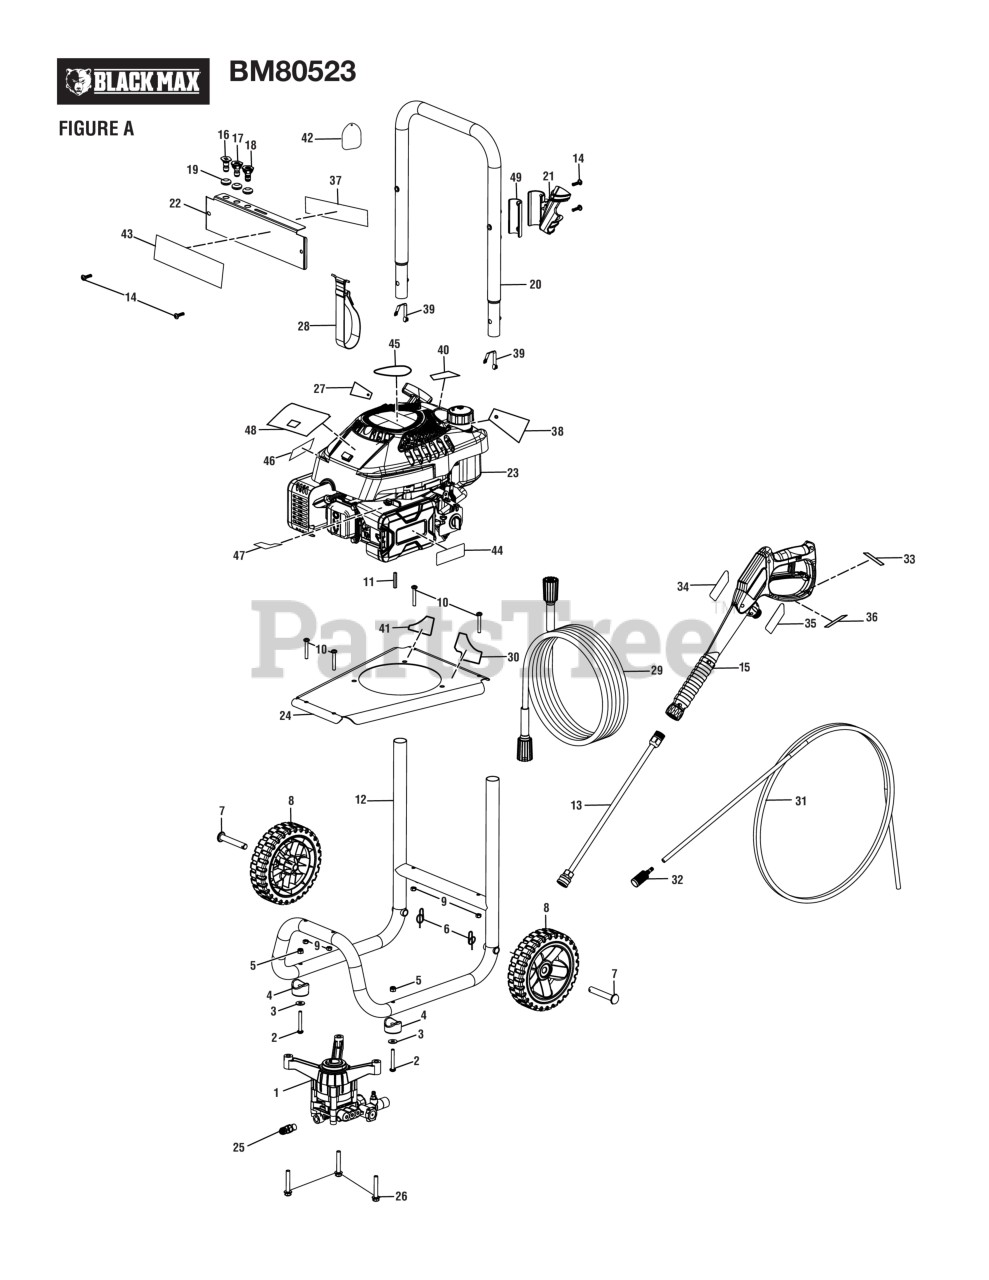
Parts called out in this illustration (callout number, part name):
1	PUMP, HIMORE ALUM HEAD, VERTICAL, 2300PS
2	Screw (1/4-20 x 1.85 in., T30 Torx Pan Hd.)
3	Washer (1/4 in.)
4	Rubber Foot
5	Lock Nut (1/4-20 in.)
6	Hitch Pin
7	Wheel Axle
8	WHEEL ASSEMBLY
9	Lock Nut (M6 x 1)
10	Bolt (M6 x 42 mm, T30 Torx Hex Hd.)..
11	Output Shaft Key (3/16 x 35 mm)
12	Main Frame Assembly
13	Spray Wand Assembly
14	Screw (M6 x 20 mm, Phillips Hd.)
15	Trigger Handle
16	Soap Nozzle (Blue)
17	Nozzle, 25° (Green)
18	40deg Nozzle
19	Rubber Nozzle Grommet
20	Handle Assembly
21	Trigger Handle Holder
22	Face Panel
23	Engine
24	ENGINE PLATE
25	Thermal Release Valve.
26	Hex Bolt (M8 x 50 mm, Flange Hd.)
27	Label (Oil Dipstick Hangtag)
28	Hose Holder Strap
29	HOSE, 25 FEET, 1/4 INCH
30	Add Oil Label
31	Detergent Injection Tube
32	Detergent Injection Filter
33	Label (Trigger Handle Warning, French & Spanish)
34	Trigger Handle Logo Label
35	Trigger Handle Warning Label (English)
36	Trigger Handle Rating Label
37	Quick Start Label
38	Danger Hang Tag
39	Lock Button w/Spring Clip
40	No E85 Label
41	LABEL, DANGER, ENGLISH ONLY
42	Nozzle Hang Tag
43	Performance Label
44	Label (Inquiries Blackmax)
45	Logo Label
46	Hot Surface & Exhaust Label
47	Choke Label
48	LABEL, ON/OFF-NOZZLE SELECTION
49	Rubber Gasket
